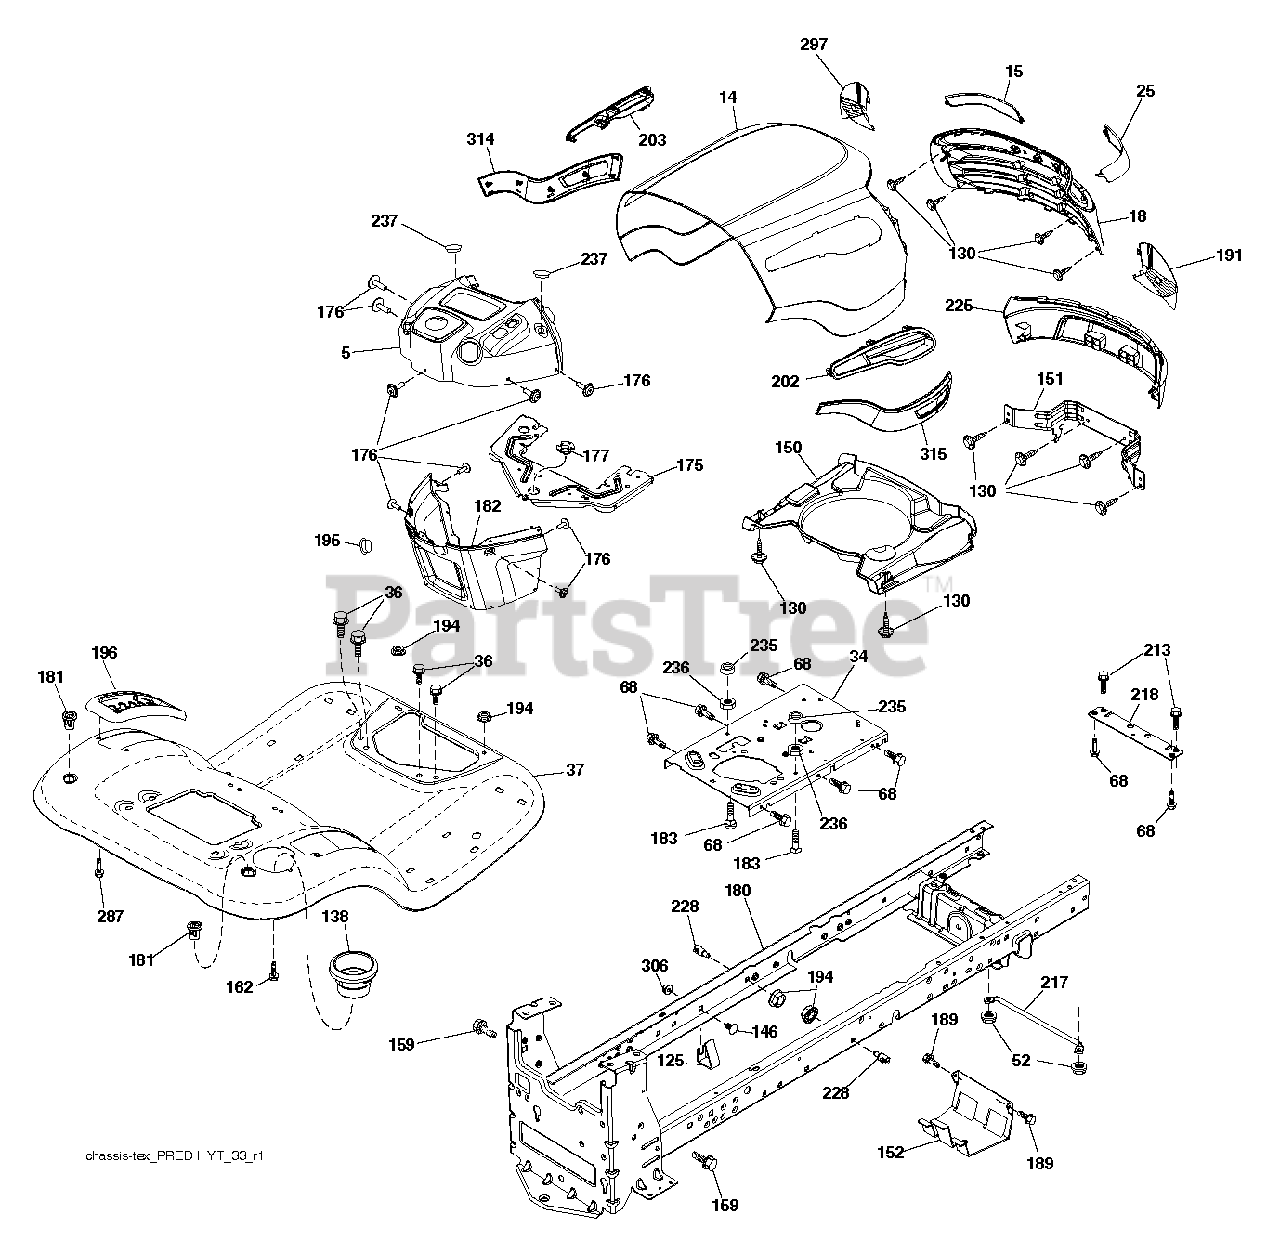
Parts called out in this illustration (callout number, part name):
36	SCREW 5/16"
52	LOCKNUT
125	Fuel Line Clip
130	SCREW.#10 X 0.750.BOS THREAD
138	CUPHOLDER.TL.TEX.BLACK
146	BOLT.RDHD.SHT.SQNK.3
150	PREDATOR.YT.GT.HOOD.A
152	SHIELD BROWNING
159	SCREW, 3/8-16X3/4
162	SCREW.HI-LO.CONSOLE
175	PLATE.CROSSMEMBER.HUSQ
176	SCREW.#10-24X5/8.RN.QU
177	BUSHING STEERING
180	CHASSIS
181	FEND/FTRST.PCH.CPH.NFW
182	DASH.LOWER.COMMON.12V.ADAPTOR
183	BOLT.5/16-18X1-1/4 FULL THD
189	SCREW
194	NUT LOCK HEX FLANGE 5/16-18
195	PLUG.HOLE.DASH.LOWER.12V.BLK
196	CONSOLE.ASM.DECKLFT.BL/RBT.TLT
202	VENT.SIDE.RH.PRED2.GTYT.JONS
203	VENT.SIDE.LH.PRED2.GTYT.JONS
213	BOLT
217	ROD.PIVOT.HOOD
218	X-PIECE.HOOD.STOP.NON/
228	STUD.FASTNER.W/ANTI-ROTATE
235	SPACER FENDER
236	NUT.CENTERLOCK.5/16-
237	PLUG.MOUNT.CARGO.BLK
306	NUT LOCK FLG 3/8-16 UNC
314	TRIM.SIDE.YT46/PRED2.LH.BL
315	TRIM.SIDE.YT46/PRED2.RH.BL
